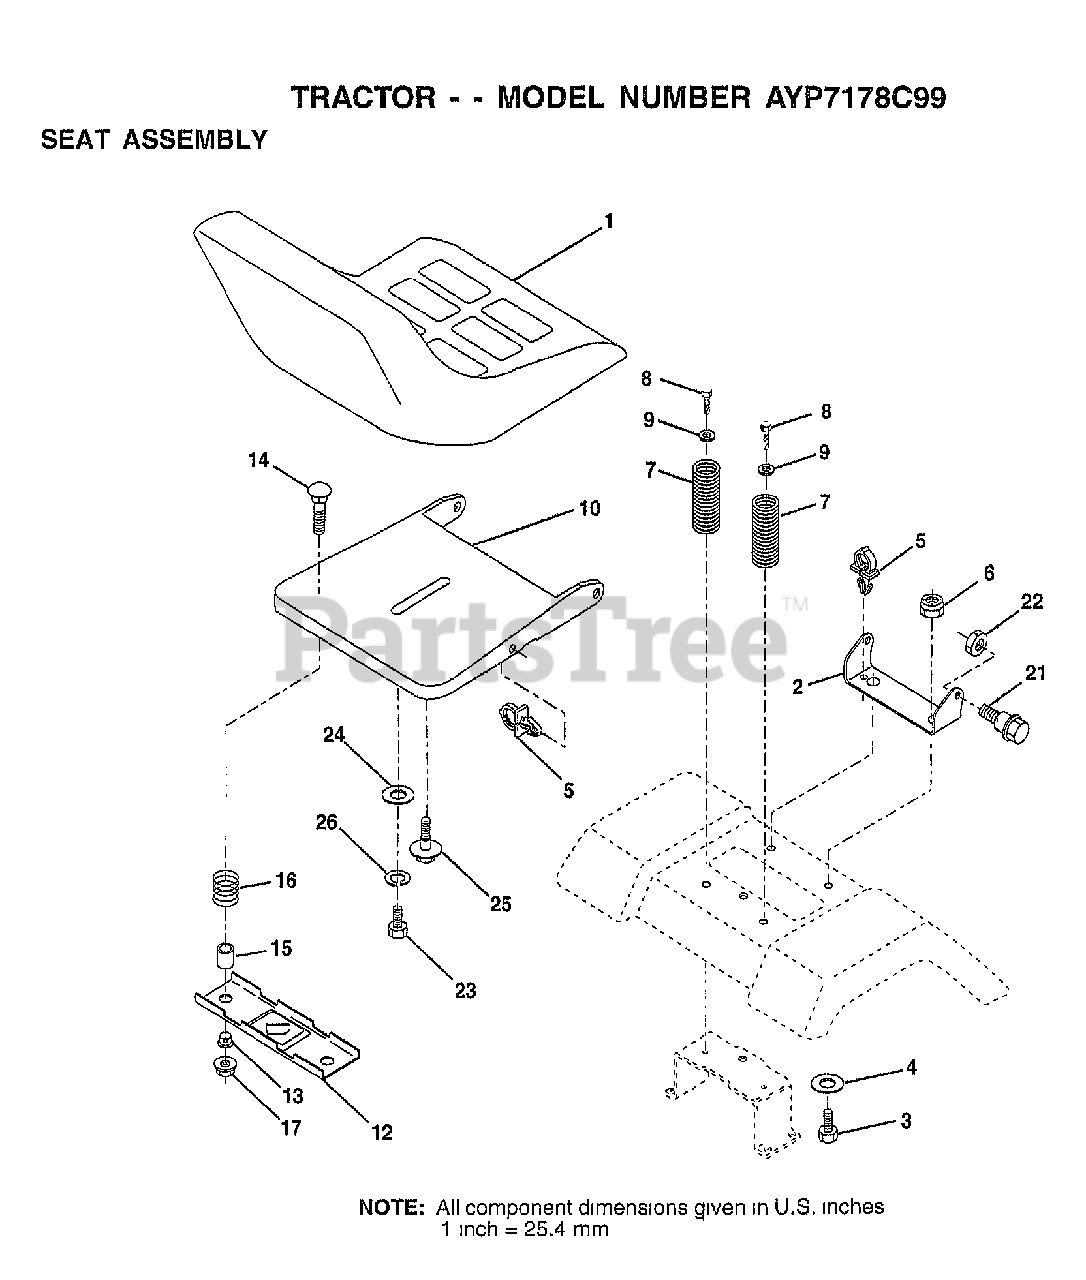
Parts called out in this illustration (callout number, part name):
1	SEAT.2400/1416.BK
2	BRACKET PVT SEAT
3	BOLT
4	WASHER PM
5	CLIP.PUSH-IN.HING
6	NUT
7	SPRING COMPRESSIO
8	SCREW
9	WASHER
10	PAN-SEAT
12	BRKT SWITCH
13	BUSHING
14	BOLT-RD HD SQ NK
15	SPLIT SPACER
16	SPRING
21	"BOLT,SHOULDER"
22	NUT
23	BOLT
24	WASHER
25	"BOLT,SHOULDER"
26	LOCKWASHER
